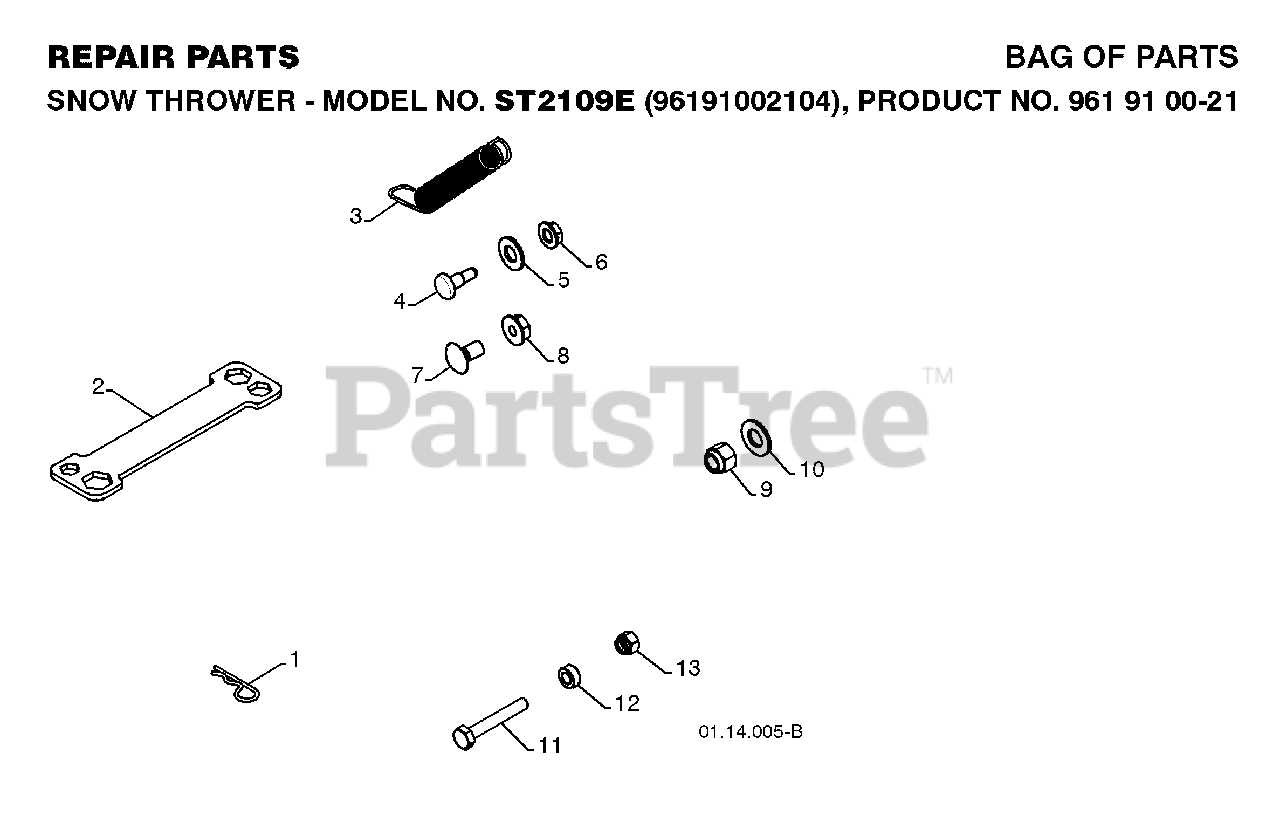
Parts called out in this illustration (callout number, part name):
1	SPRING RETAINER
2	RP WRENCH, SNOWTHROWER
4	BOLT, SHOULDER
5	WASHER, NYLON FRICTION
6	NUT.HEX.FLANGE.1/4
7	BOLT
8	NUT, LOCK 5/16-18
9	NUT
11	BOLT, SHEAR
13	LOCKNUT
